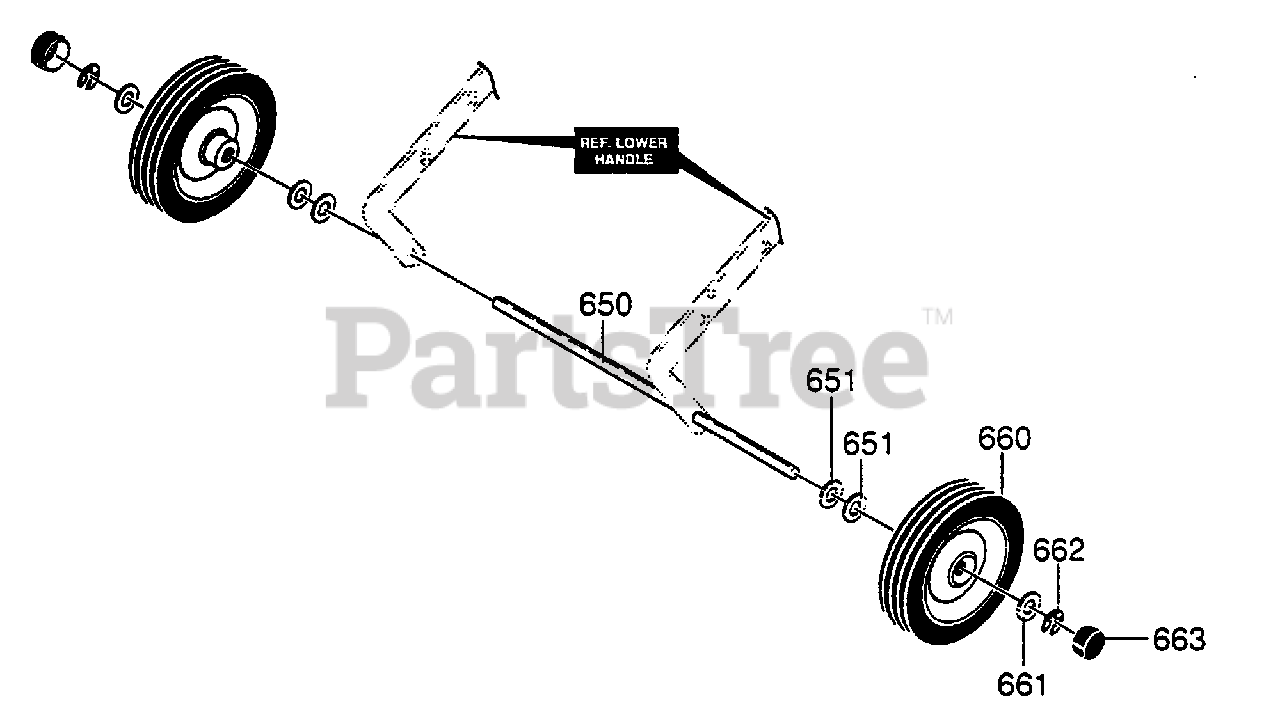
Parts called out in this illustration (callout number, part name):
650	AXLE, SHAFT 7" WHEEL
651	FLATWASHER .391 X 1.00 X .125
660	TIRE & RIM 7 X 1.50 SEPU
661	FLATWASHER .391 X 1.00 X .125
662	RING, RET E
663	HUB CAP
